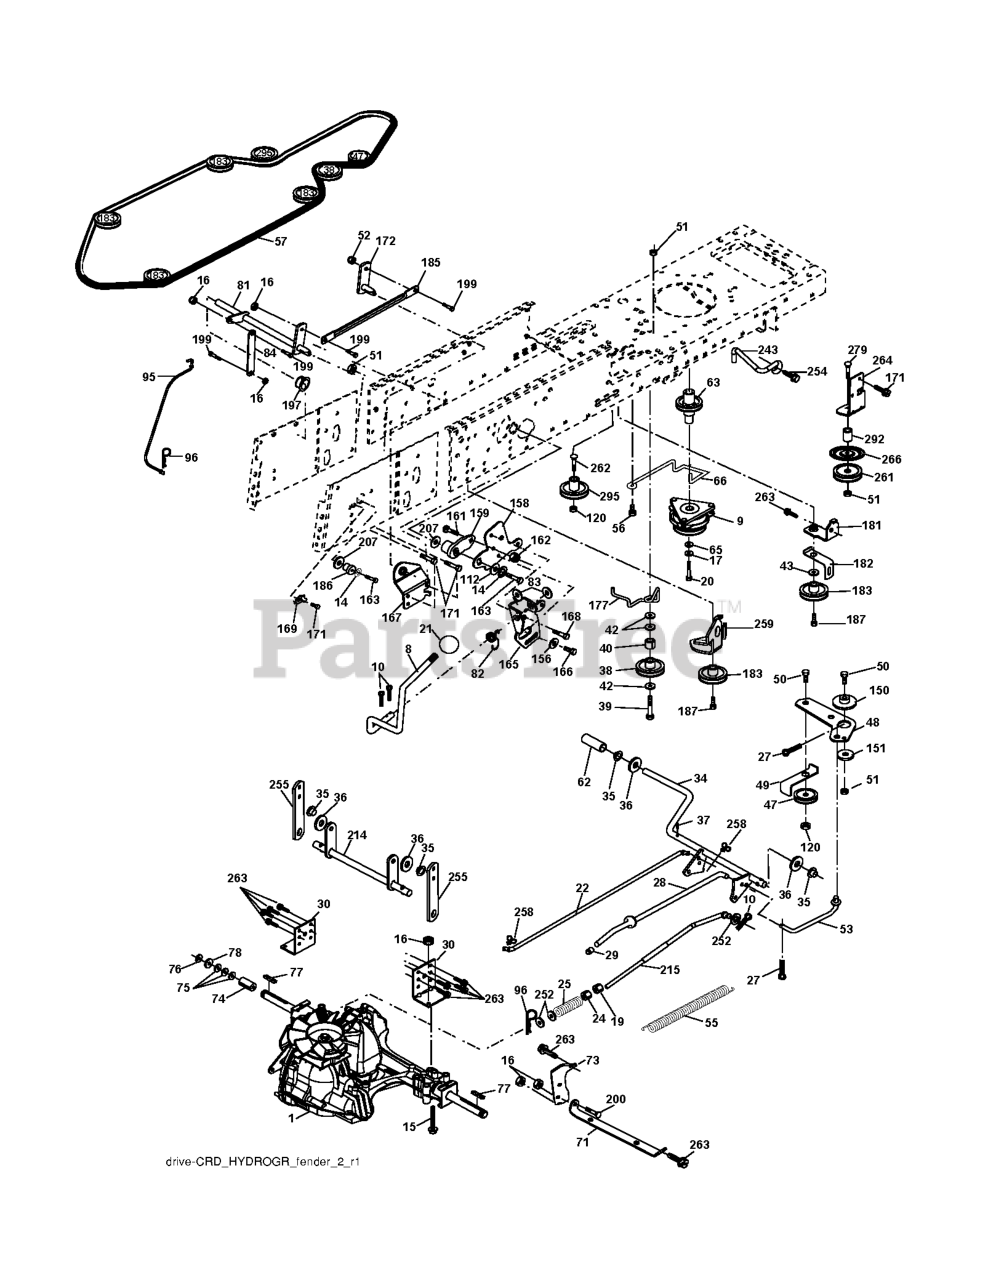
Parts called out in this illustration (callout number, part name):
8	ROD SHIFT FENDER ADJUST LT
9	CLUTCH.ELECTRIC.OGURA.EURO.
10	PIN COTTER
14	LOCKWASHER
15	BOLT HEX 5/16-18 GR 5
16	NUT.71038.31-18.HEX.NYLOCK
19	NUT
20	BOLT HEX 7/16-20X4-1/4"
21	KNOB.DUCKHEAD.1/2
22	ROD
24	NUT
25	SPRING BRAKE ROD
27	COTTER PIN
28	ROD, PARKING BRAKE
29	CAP
30	BRKT, TRNSXLE MNT 20"
34	SHAFT, FOOT PEDAL
35	BEARING.NYLON
37	DRIVE PIN
38	PULLEY.FLAT
42	WASHER
47	IDLER PULLEY
48	BELLCRANK, CLUTCH
49	RETAIN BELT
50	BOLT.3/8-16X1.50
52	LOCKNUT
53	LINK.CLUTCH.7.66.2005
55	SPRING, RETURN LT
56	SCREW.3/8-16
57	V-BELT 113"
62	PEDAL COVER T
63	PULLEY.ENGINE.CVX.LT
65	LOCKWASHER
66	KEEPER BELT ENGINE
71	STRAP TORQUE LH HYDRO
73	STRAP TORQUE RH HYDRO
74	SPACER AXLE
77	SQUARE KEY
81	ASM.CROSS.SHAFT.REAR.CRD.0510
82	SHIFT SPRING
83	WASHER
84	LINK.PNT.TRANSAXLE.0510.CRD
95	LINK
96	RETAINER M
120	NUT LOCK FLG 3/8-16 UNC
150	BUSHING.BELLCRANK.GRD.DR
151	WASHER 12/32X2X10GA
156	WASHER.SRRTD.5/16
158	BRACKET
159	RB HUB.SHIFT
161	BOLT
162	NUT.CROWNLOCK.1/4
165	RP BRACKET
166	CAPSCREW.HXHD.FLG.5/16-18X.625
167	BRACKET.SUPT.SHIFT.CRD
168	BOLT.SHOULDER.5/16-18X
169	PLATE.FASTENING.CROSS.SHAFT
172	LINK
181	BRACKET
182	BELT GUIDE
183	PULLEY.V-IDLER.GRND.DR
185	LINK
186	HUB.TAPERED.ROUND.CRD
187	BOLT.5/16-18X1.25
197	NYLINER SNAP 5/8" ID
199	BOLT SHOULDER 5/16-18 UNC
207	WASHER NYL
214	LEVER
215	ROD
243	BRACKET, ANTI-ROTATION
252	WASHER
254	SCREW 3/8-16X1
255	SHAFT
258	CLIP RETAINER
259	BRACKET
261	FLAT IDLER PULLEY
263	SCREW, 3/8-16X3/4
266	PROTECTOR
292	SPACER
295	PULLEY IDLER COMPOSITE
